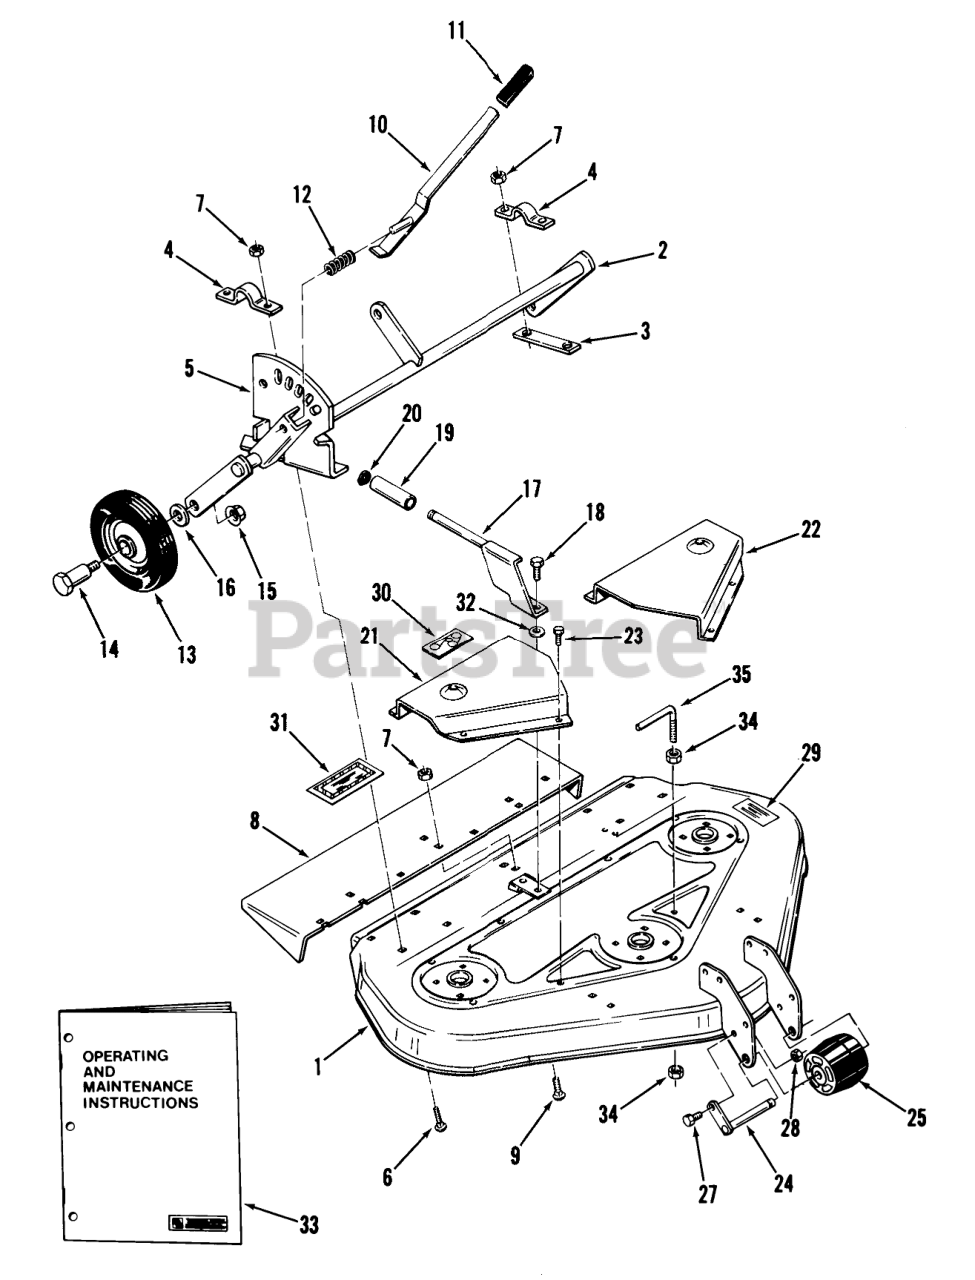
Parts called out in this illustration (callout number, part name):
2	ASSY GAGE WHEEL S *R
12	SPRING-COMPRESSION
16	SHIM-WASHER
18	Bolt
23	Bolt
32	WASHER
33	Operating and Maintenance Instructions
